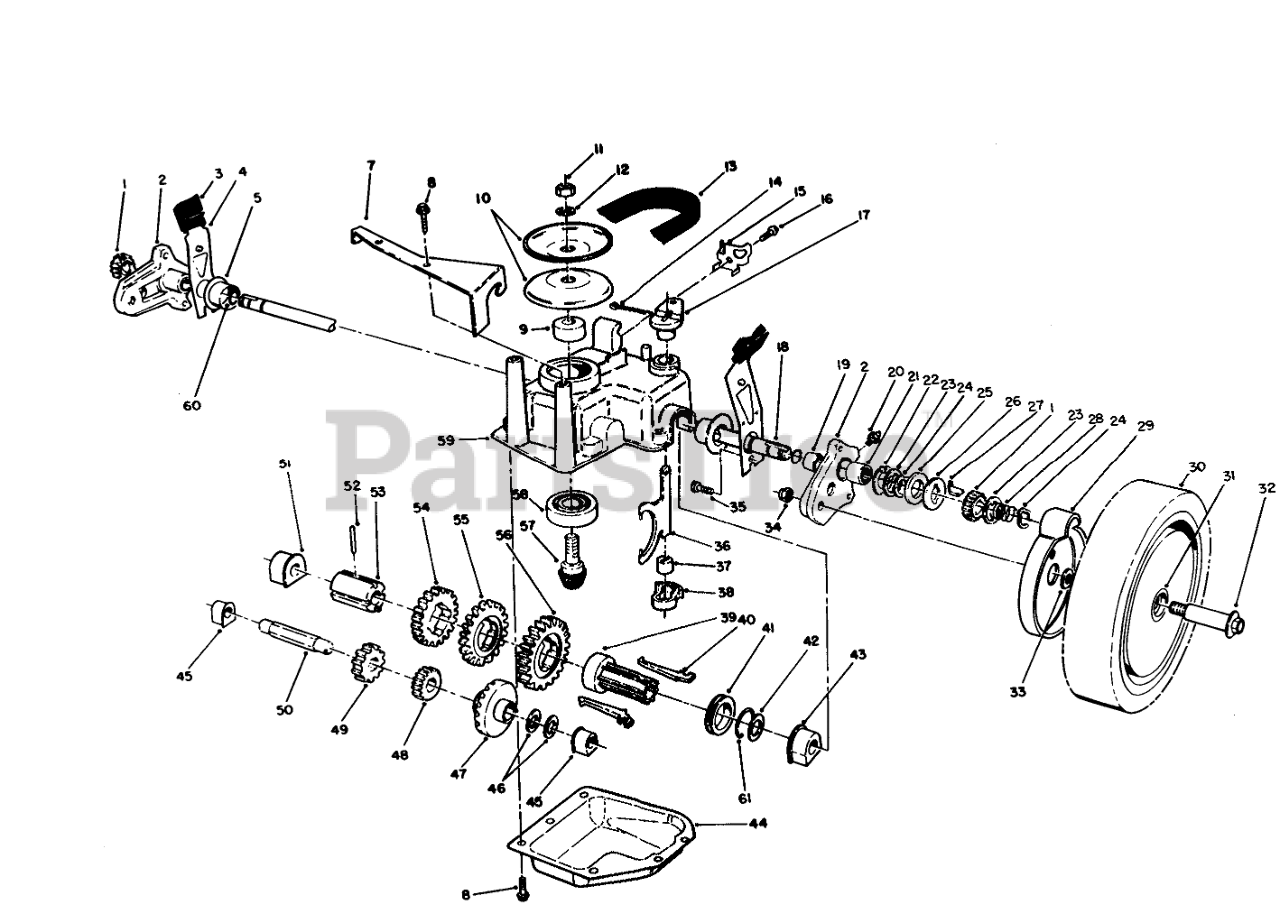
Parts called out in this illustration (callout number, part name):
1	GEAR-PINION
2	Pivot Arm Assembly (Incl. Ref #19, 20, & 21)
3	KNOB-ARM
4	SPRING ARM ASM SP
5	CAP-END
7	Bracket-Guide
8	SCREW-HWHTF
9	SPACER
10	Pulley Half
11	NUT-HEX
12	WASHER-FLAT
13	V-BELT E
14	PIN-COTTER
15	CLAMP-CABLE
16	SCREW-HWHTF
17	LEVER-SHIFT
18	SHAFT-OUTPUT
19	BUSHING
20	FITTING-GREASE
21	BEARING-ROLLER
22	WASHER-ARM, PIVOT
23	WASHER-THRUST, KEYED
24	RING-CLIP, LOCKING
25	RING-FRICTION
26	WASHER-CLUTCH
27	KEY-ROCKING, LH
28	SPRING-COMPRESSION
29	COVER-WHEEL
30	Wheel-Tire & Gear Ass-y (Incl. Ref. #31)
31	BUSHING
33	SPACER-COVER, WHEEL
34	Nut
35	SCREW-HWH
36	YOKE-SHIFT
37	BUSHING-YOKE
38	RETAINER-FORK, SHIFT
39	SLEEVE-KEY, SHIFT
40	KEY-SHIFT
41	COLLAR-SHIFT
42	WASHER-PLAIN
43	BUSHING-OUTPUT
44	Cover-Gearcase
45	BUSHING
46	WASHER-THRUST
47	Gear-Bevel
48	PINION-20T
49	PINION-25T
50	SHAFT-INTERMEDIATE
51	BUSHING
52	PIN-SPRING
53	SLEEVE-GEAR
54	GEAR-39T
55	GEAR-44T
56	GEAR-49T
57	Gear-Pinion
58	BEARING-BALL
59	CASE-GEAR, UPPER
60	O-RING
61	CLIP-SPRING
